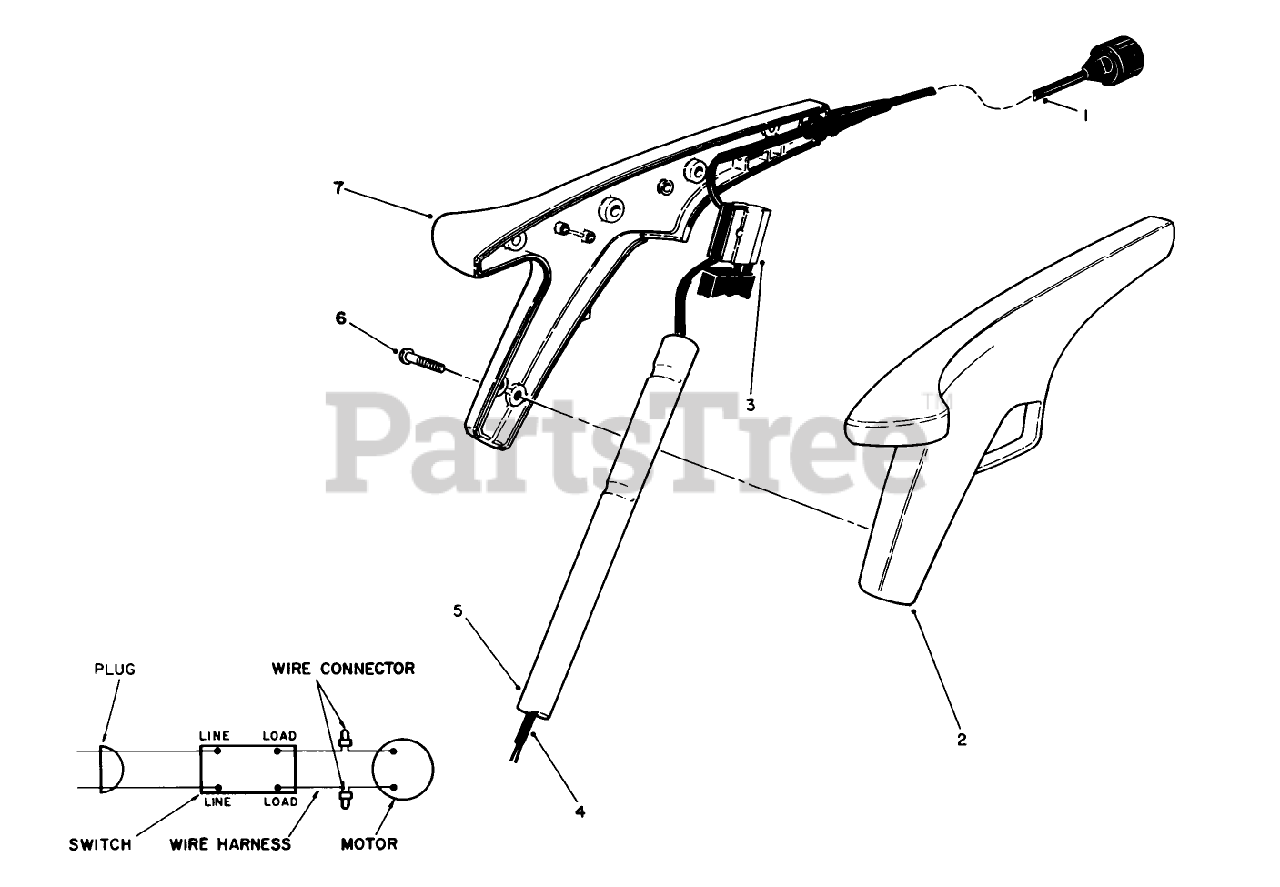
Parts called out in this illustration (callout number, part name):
1	CORD-SUPPLY
2	HAND GRIP, 8" - L.H.
3	SWITCH SINGLE SPEED
4	WIRE HARNESS
5	TUBE EXTENSION
6	#8 X .625" PHILPS PAN H
7	HAND GRIP, 8" - R.H.
